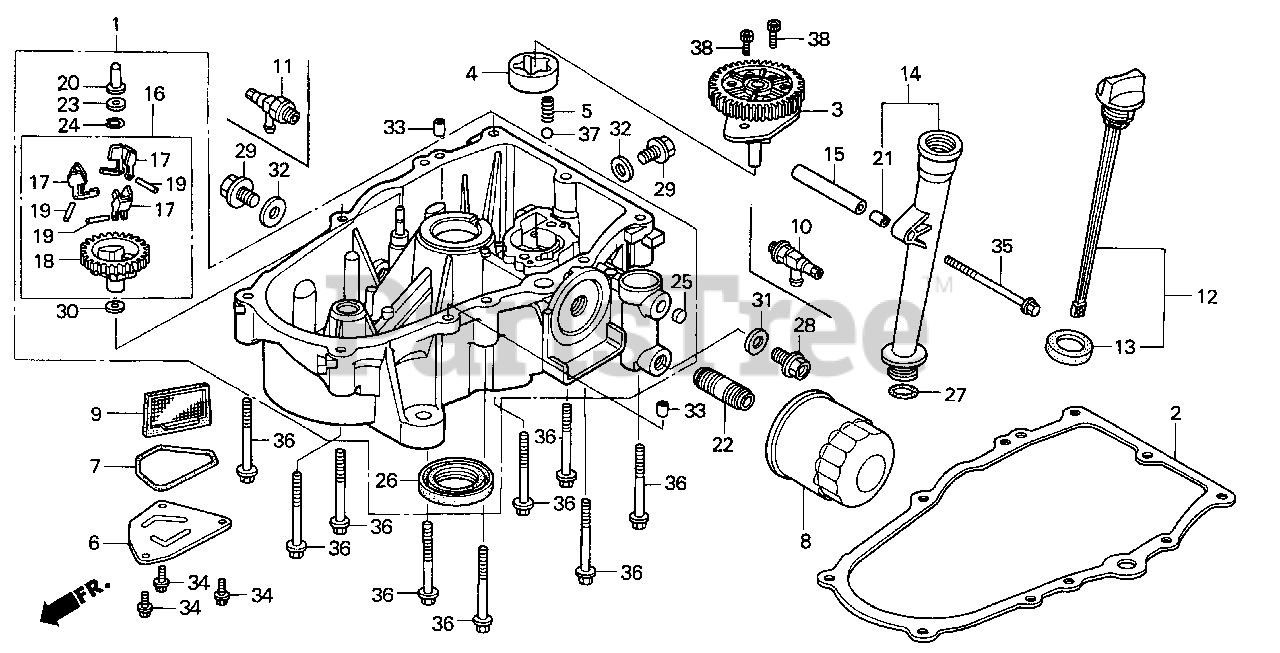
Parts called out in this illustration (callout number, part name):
1	PAN ASSY., OIL
2	GASKET, CASE COVER
3	COVER ASSY., OIL PUMP
4	ROTOR, OIL PUMP (OUTER)
5	SPRING, RELIEF VALVE
6	PLATE, OIL FILTER
7	O-RING, OIL PLATE
8	FILTER, OIL (TOYO ROKI) (SOLD IN MULTIPLES OF 30)
8	FILTER, OIL (SOLD INDIVIDUALLY)
9	SCREEN, OIL FILTER
10	VALVE, DRAIN (14X1.5)
11	VALVE, OIL SHUT-OFF
12	CAP ASSY., OIL FILLER
13	GASKET, OIL FILLER CAP
14	EXTENSION, OIL FILLER
15	COLLAR, FILLER SETTING
16	GOVERNOR ASSY.
17	WEIGHT, GOVERNOR
18	HOLDER, GOVERNOR WEIGHT
19	PIN, GOVERNOR WEIGHT
20	SLIDER, GOVERNOR
21	COLLAR, EXTENSION
22	HOLDER, OIL FILTER
23	WASHER (6X16)
24	CLIP, GOVERNOR HOLDER
25	PLUG, SEALING (10MM)
26	OIL SEAL (38X58X9)
27	O-RING (22.5X2.2)
28	BOLT, DRAIN PLUG (14MM)
29	BOLT, DRAIN PLUG (20MM)
30	WASHER, PLAIN (6MM)
31	WASHER, DRAIN PLUG (14MM)
32	WASHER, DRAIN PLUG (20MM)
33	PIN A, DOWEL (8X14)
34	BOLT, FLANGE (6X14)
35	BOLT, FLANGE (6X100)
36	BOLT, FLANGE (8X50)
37	BALL, STEEL (#12) (3/8)
38	BOLT, SOCKET (6X16)
